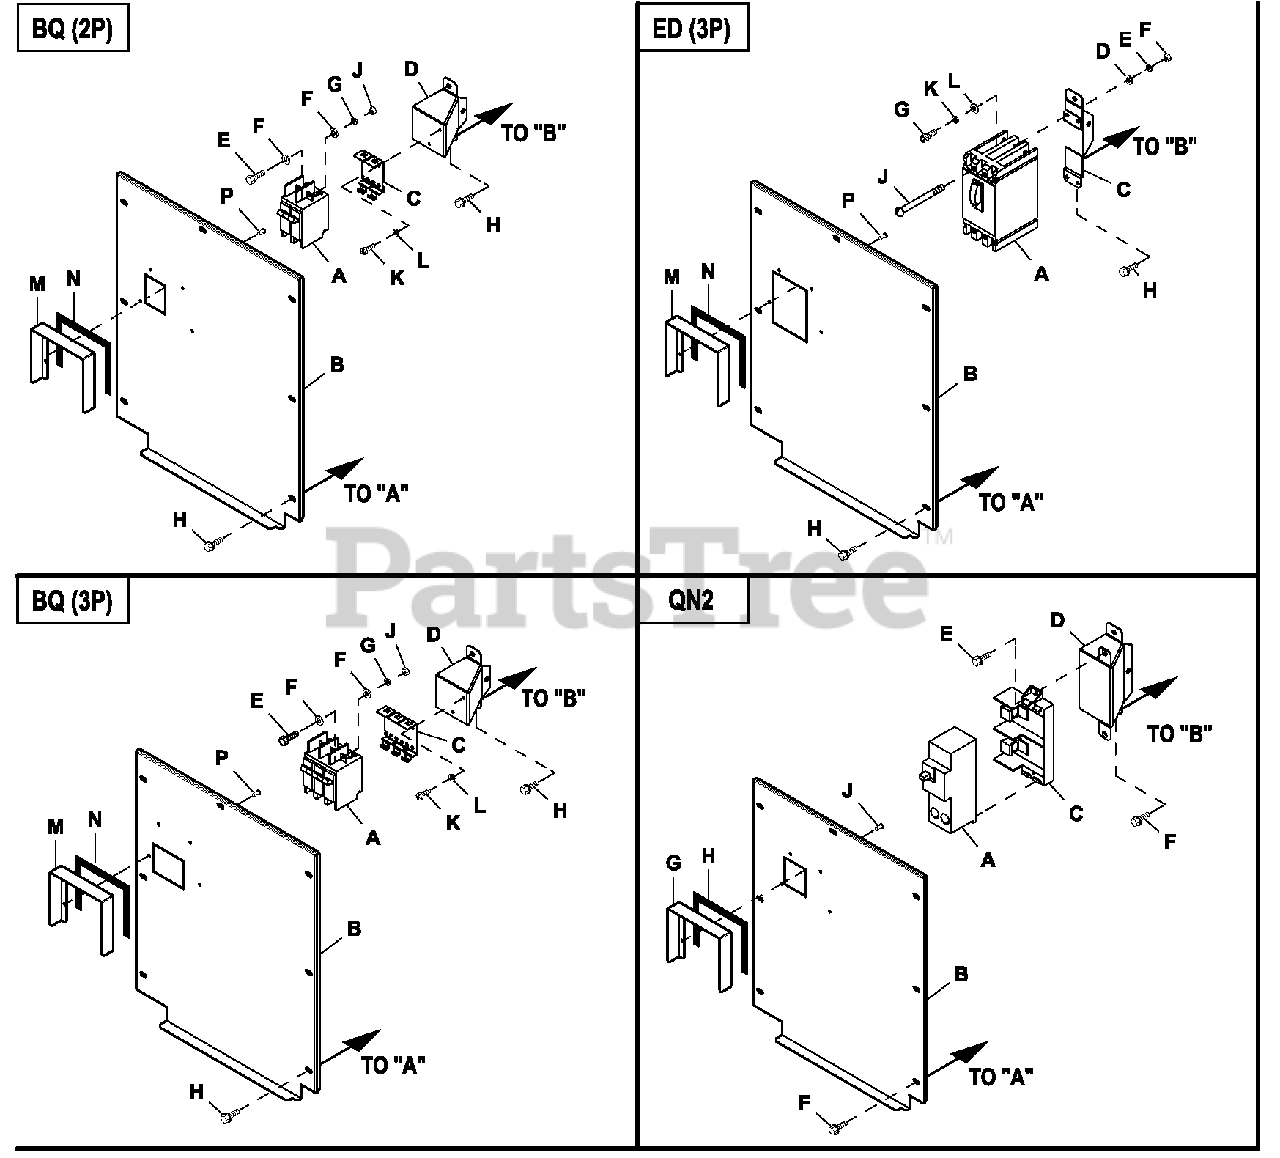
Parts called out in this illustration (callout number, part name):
A	CB 0090A 2P 240V S BQ2 LL
B	COVER CB S BQ2C1 CONBOX
C	BRKT CB MTG BACK
D	CIRCUIT BREAKER SUPPORT (BQ)
E	SCREW HHC M5-0.8 X 20 G8.8
F	WASHER FLAT #10 ZINC
G	WASHER LOCK M5
H	SCREW HWHT M6-1 X 16 N WA Z/JS
J	N UT HEX M5-0.8 G8 CLEAR ZIN C
K	SCREW PHTT M4-0.7 X 12 ZP
L	WASHER LOCK#8-M4
M	SHIELD CB HA N DLE CO N BOX
N	TAPE ELEC 1/2 FOAM
P	RIVET POP .125 X .275 SS
A	CB 0080A 3P 240V S BQ3 LL
B	CB 0100A3P 240V S BQ3 LL
C	COVER CB S BQ3C1 CONBOX
D	MTG TRACK BQ SIEME N S CB 3P
E	CIRCUIT BREAKER SUPPORT (BQ)
F	SCREW HHC M5-0.8 X 20 G8.8
G	WASHER FLAT# 1 0 ZIN C
H	WASHER LOCK M5
J	SCREW HWHT M6-1 X 16 N WA Z/JS
K	N UT HEX M5-0.8 G8 CLEAR ZIN C
L	SCREW PHTT M4-0.7 X 12 ZP
M	WASHER LOCK#8-M4
N	SHIELD CB HA N DLE CO N BOX
P	TAPE ELEC 1/2 FOAM
A	CB 0050A 3P 480V S ED4 LL
B	COVER CB S ED3C1 CONBOX
C	CIRCUIT BREAKER SUPPORT (ED)
D	WASHER FLAT #8 ZIN C
E	WASHER LOCK#8-M4
F	N UT HEX #8-32 STEEL
G	SCREW SHC 1/4-28 X 3/4 G8.8 NZ
J	SCREW RHM #8-32X4-1/2
K	WASHER LOCK M6-1/4
L	WASHER-STEP 1/2ODX9/32ID BRASS
A	CB 0150A2P 240V S QN2 LL
B	COVER CB S QN2C1 CONBOX
C	BASE , QN CIRCUIT BREAKER
D	BREAKER SUPPORT BRACKET 30KW
E	SCREW HHTT M5-0.8 X 10 BP
F	SCREW HWHT M6-1 X 16 N WA Z/JS
G	SHIELD CB HANDLE CONBOX
H	TAPE ELEC 1/2 FOAM
J	RIVET POP .125 X .2
